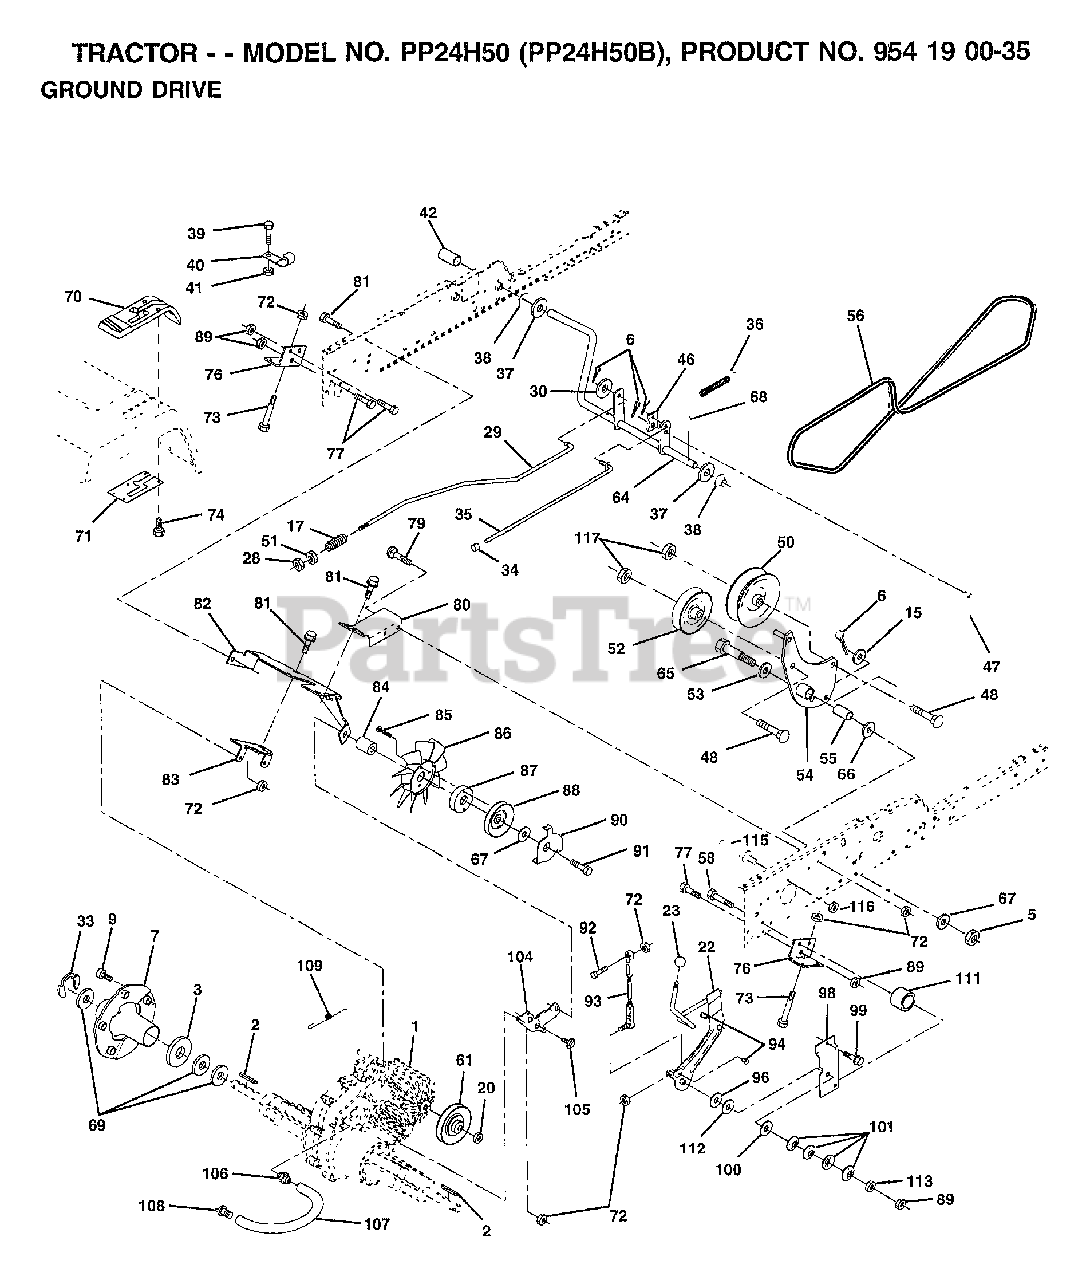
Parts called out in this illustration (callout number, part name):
2	KEY 1/4 X 2.5
3	WASHER T
6	COTTER PIN
7	HUB WHEEL ASM
9	BOLT.HUB.WHL.REAR
15	WASHER
17	SPRING ROD BRAKE
22	ARM ASM SHIFT
23	KNOB.DUCKHEAD.1/2
28	NUT
29	ROD BRAKE
30	WASHER HYT
33	E RING HYT
34	PLUNGER CAP T
35	ROD BRAKE PART GT
36	SPRING.GRND.DRIVE
37	WASHER
38	BUSHING.NYLINER
39	SCREW
40	ACT-SWITCH T
42	"COVER,PEDAL"
46	RETAINER.SPRING
47	ROD.CLUTCH
48	BOLT.3/8-16X1.50
50	FLAT IDLER PULLEY
52	PULLEY.IDLER.V.GR
53	WASHER T
54	CLUTCH.ARM.ASM
55	"LY, BEARING"
56	BELT-V 84.5
58	SCREW.3/8-16X1-1/2.SMGML
61	PULLEY TRANSAXLE
64	SHAFT-BRAKE/CLUTC
65	AXLE BOLT
66	WASHER.HARD.BLADE
67	WASHER
68	ROLL PIN STD
69	WASHER
70	CONSOLE.SHIFT.AUTO.YT/GT.BLACK
71	"PLATE CONSOLE,SFT"
72	NUT
73	BOLT.HEX.FLGHD.
74	SCREW HEXWSH H-L
76	BRACKET TRAN VGTH
77	BOLT
79	BOLT
80	BRACKET TORQUE RH
81	SCREW
82	BRACKET.MTG.FAN
83	STRAP TORQUE MID
84	SPACER
85	SCREW YTV
86	"FAN 7"" HYDRO"
87	ADAPTER FAN
88	PULLEY FAN
89	NUT GTV
90	KEEPER BELT
91	SCREW.HXWSH.3/8
93	LINK ASM SHIFT
94	XMAS TREE FASTNER
96	WASHER NICKEL PLT
98	BRACKET SHIFT
99	SCREW LT
100	WASHER COMPRESSIN
101	WASHER-BELLVILLE
104	BRACKET IDLER
105	SCREW CRT
106	O-RING.ASM.70110
107	"LINE FUEL,HYD 15"""
108	CAP.VENT.70109
109	SPRING BRAKE
111	"SPACER-LEVER,SHIF"
112	"WASHER-NYLON,HIGH"
113	NUT
115	"KEEPER,DRIVE BELT"
116	"NUT HEX,LOCK,FLAN"
